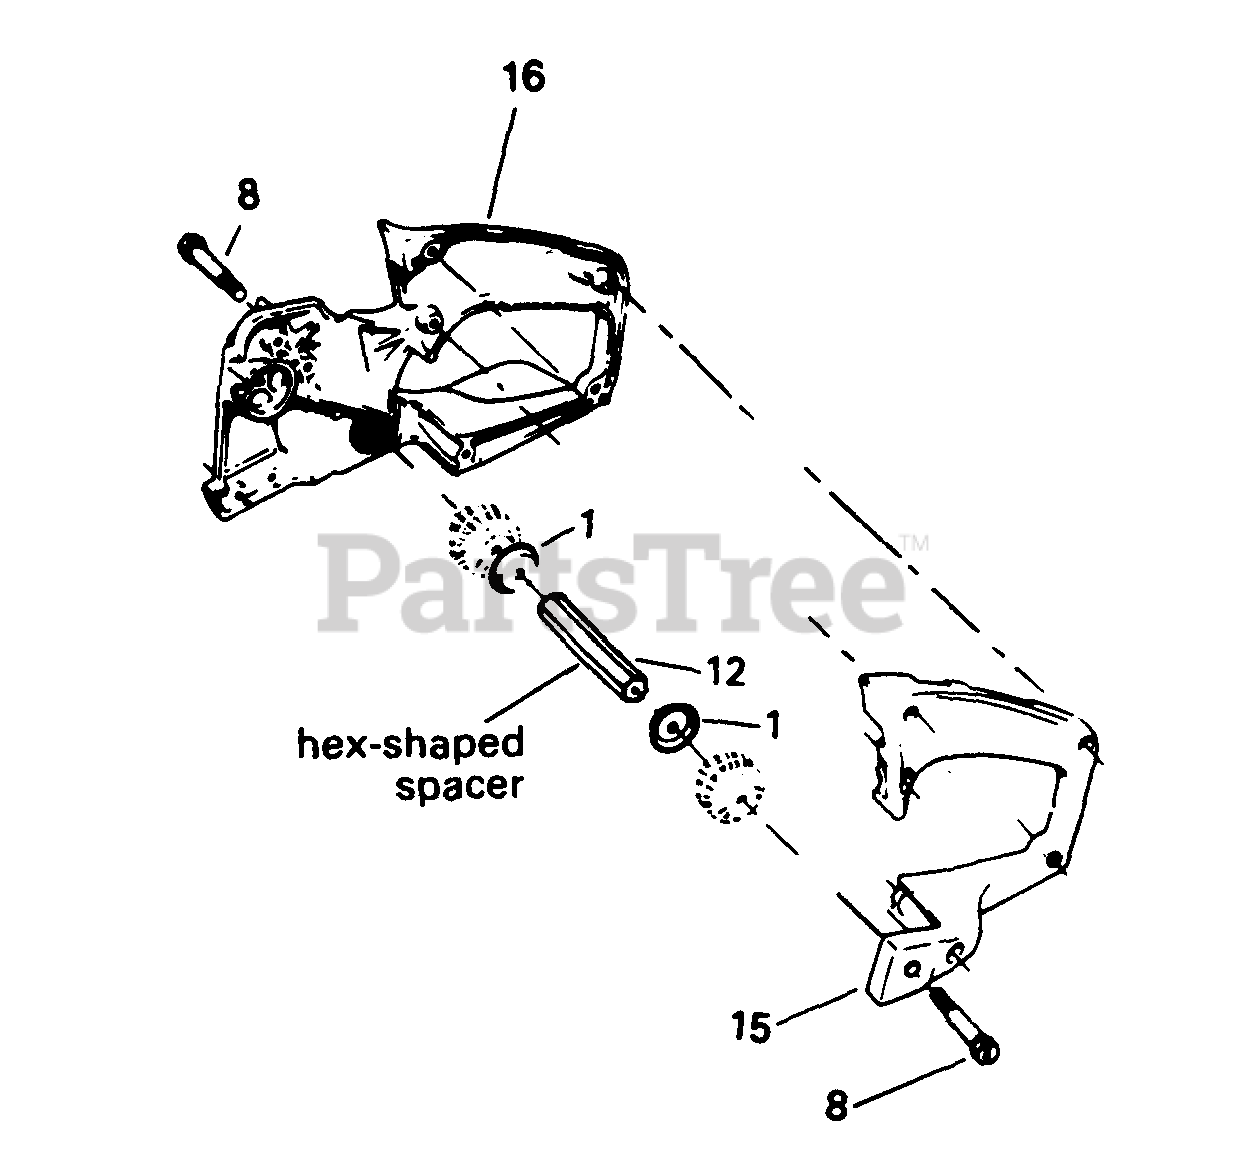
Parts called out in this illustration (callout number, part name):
1	Cup Isolator
6	Handle Brace
6	Use on Guide Bar Powerhead
6	Use on Bow Guide Powerhead
7	Screw-1/4-20x3/4 Button Hd.
8	Shoulder Screw 1/4-20
12	Spacer-Center
15	Rear Handle-Left
16	Rear Handle-Right
